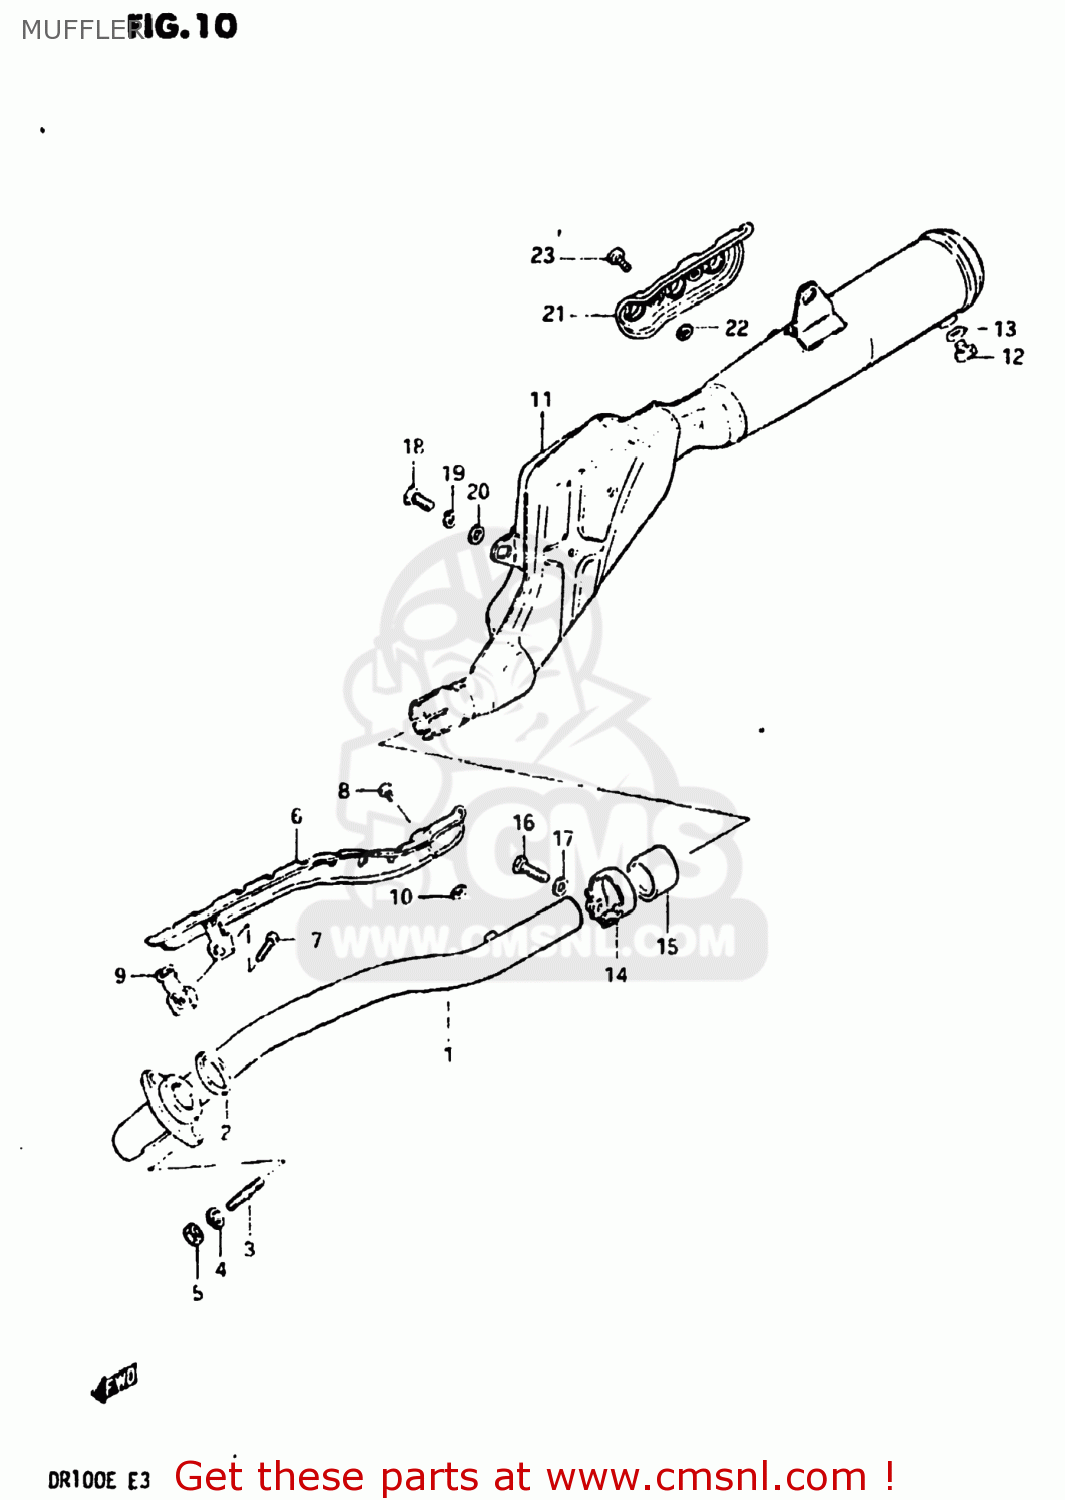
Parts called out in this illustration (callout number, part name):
1	PIPE,EXHAUST
2	GASKET,EXHAUST PIPE (NAS)
3	STUD BOLT L:20
4	LOCK WASHER
5	NUT
6	COVER,EXHAUST PIPE
7	SCREW 5X20
8	SCREW
9	CLAMP,EXHAUST PIPE COVER
10	GASKET 6.2X12X1.5 (MCA)
11	MUFFLER ASSEMBLY
12	PLUG(12X9)
13	GASKET(12X16X2) (NAS)
14	CLAMP,MUFFLER CONNECTOR
15	CONNECTOR,MUFFLER
16	BOLT 8X35
17	WASHER,8.5X16X
18	BOLT
19	LOCK WASHER
20	WASHER,8.5X16X
21	COVER,MUFFLER
22	GASKET 6.2X12X1.5 (MCA)
23	SCREW
